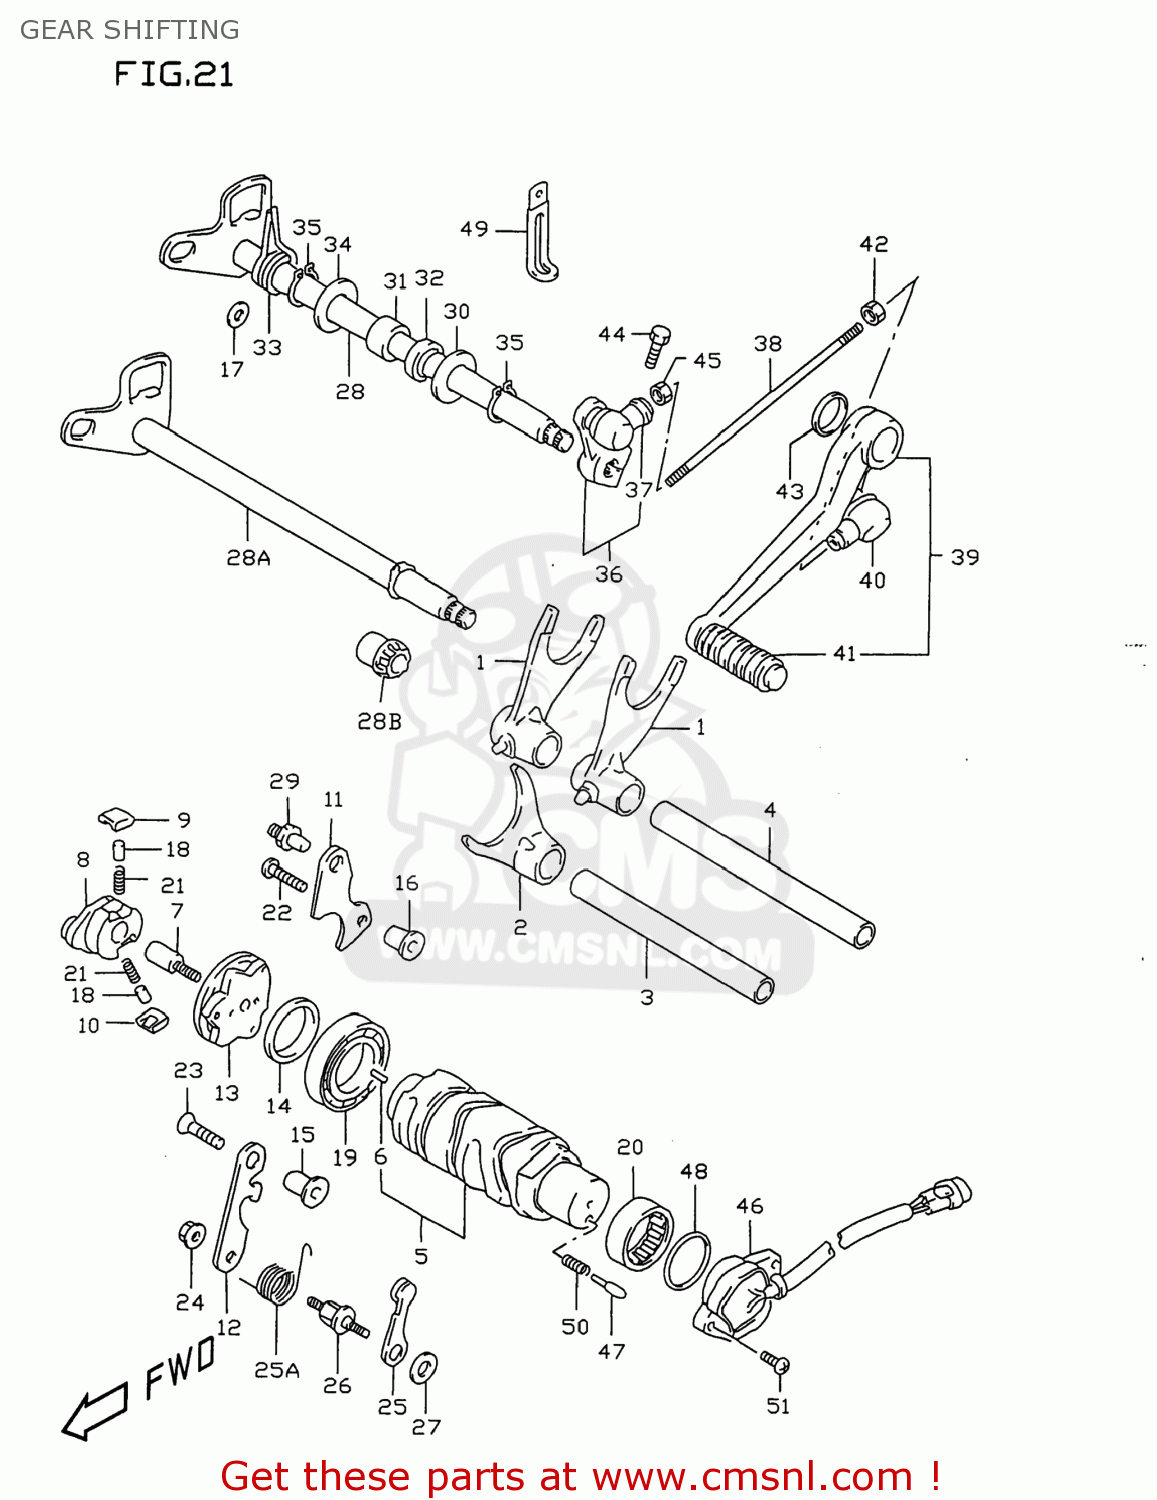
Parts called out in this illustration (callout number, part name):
1	FORK,GEAR SHIFT
2	FORK,GEAR SHIFT NO.3
3	SHAFT,GEAR SHIFT FORK
4	SHAFT,GEAR SHIFT FORK(L:128)
5	CAM,GEAR SHIFT
6	PIN
7	PIN,SHIFT CAM DRIVEN GEAR
8	SHIFTER,GEAR SHIFT CAM
9	PAWL,GEAR SHIFT NO.1
10	PAWL,GEAR SHIFT NO.2
11	LIFTER,GEAR SHIFT PAWL
12	GUIDE,GEAR SHIFT CAM
13	PLATE,GEAR SHIFT CAM
14	WASHER(25X32X3)
15	SPACER(6.1X10X16)
16	SPACER(6.1X10X16)
17	SPACER(7X10X5)
18	PIN(5X8)
19	BEARING(25X47X8)
20	BEARING(25X32X12)
21	SPRING
22	SCREW 6X30
23	SCREW
24	NUT
25	STOPPER,GEAR SHIFT CAM
25A	SPRING,SHIFT CAM STOPPER
26	SUPPORT,CAM STOPPER ARM
27	WASHER
28	SHAFT COMP,GEAR SHIFTING
28A	SHAFT,GEAR SHIFT
28B	BUSH,GEAR SHIFT SHAFT
29	STOPPER,GEAR SHIFT CAM
30	WASHER(14X29X0.8)
31	BEARING(14X20X12)
32	SEAL,OIL(14X22X6)
33	SPRING
34	WASHER
35	CIRCLIP
36	ARM,GEAR SHIFT LINK
37	COVER,DUST
38	ROD,GEAR SHIFT LINK(L:165)
39	LEVER ASSY,GEAR SHIFT
40	COVER,DUST
41	RUBBER,GEAR SHIFT PEDAL
42	NUT
43	WASHER(18X24X1)
44	BOLT
45	NUT
46	BASE ASSEMBLY,GEAR SHIFT TERMINAL
47	PIN(5X15.5)
48	O RING(D:2.4,ID:25.7)
49	CLAMP(L:45)
50	SPRING
51	SCREW
